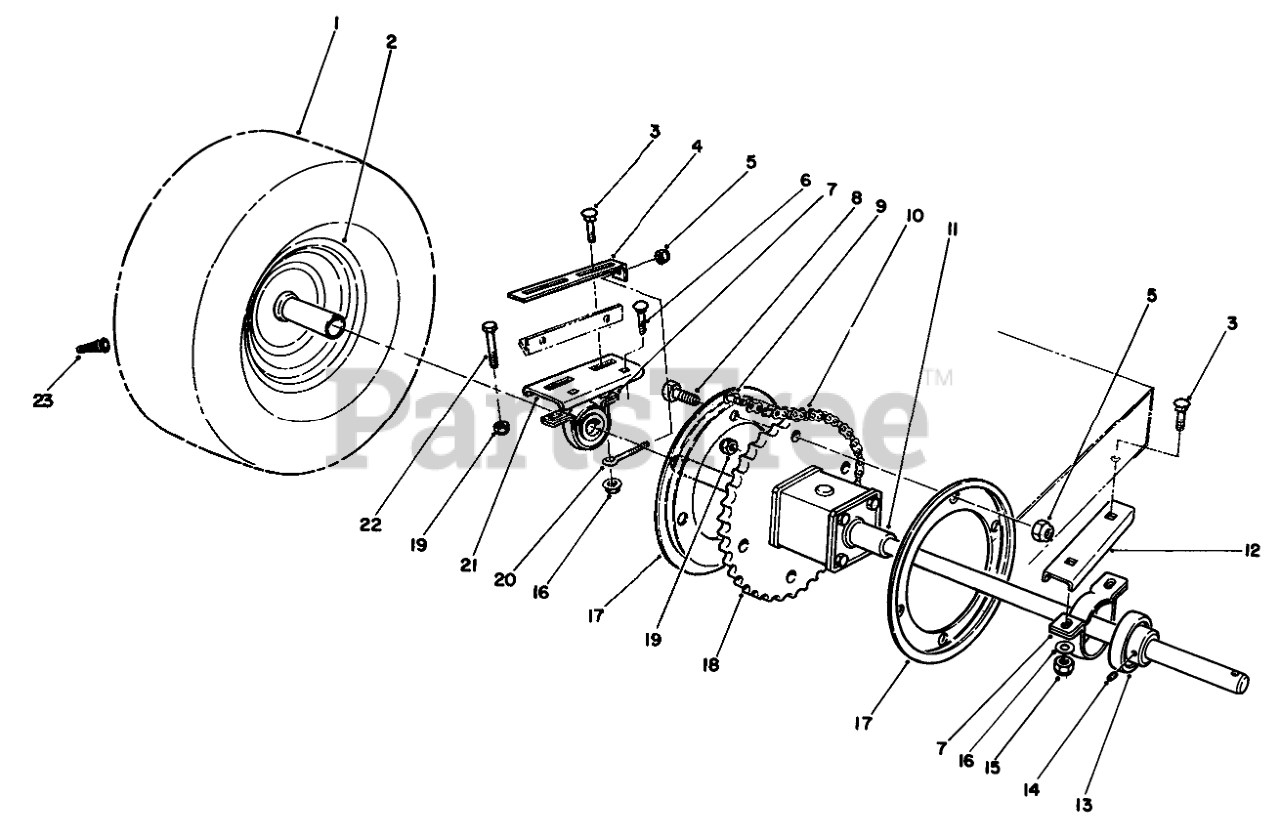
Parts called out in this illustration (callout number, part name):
1	TIRE,PNEU.13X5.00X6
2	WHEEL-REAR
3	SCREW-CARR
4	PLATE-ADJUSTING
5	NUT-LOCK, NI
6	BOLT-CARR
7	RTNR-PILLOW BLK
8	SCREW-HH
9	LINK-CHAIN
10	Chain (Incl. Ref. #9)
11	DIFFERENTIAL
12	Support L.H.
13	Bearing (Incl. Ref. #14)
14	SCREW-HSH
15	NUT-LOCK, NI
16	WASHER-FLAT
17	Guide-Chain
18	SPROCKET
19	NUT-LOCK, NI
20	SCREW-ADJUSTING
21	Support R.H.
22	AXLE MTG BOLT
23	STEM-VALVE
